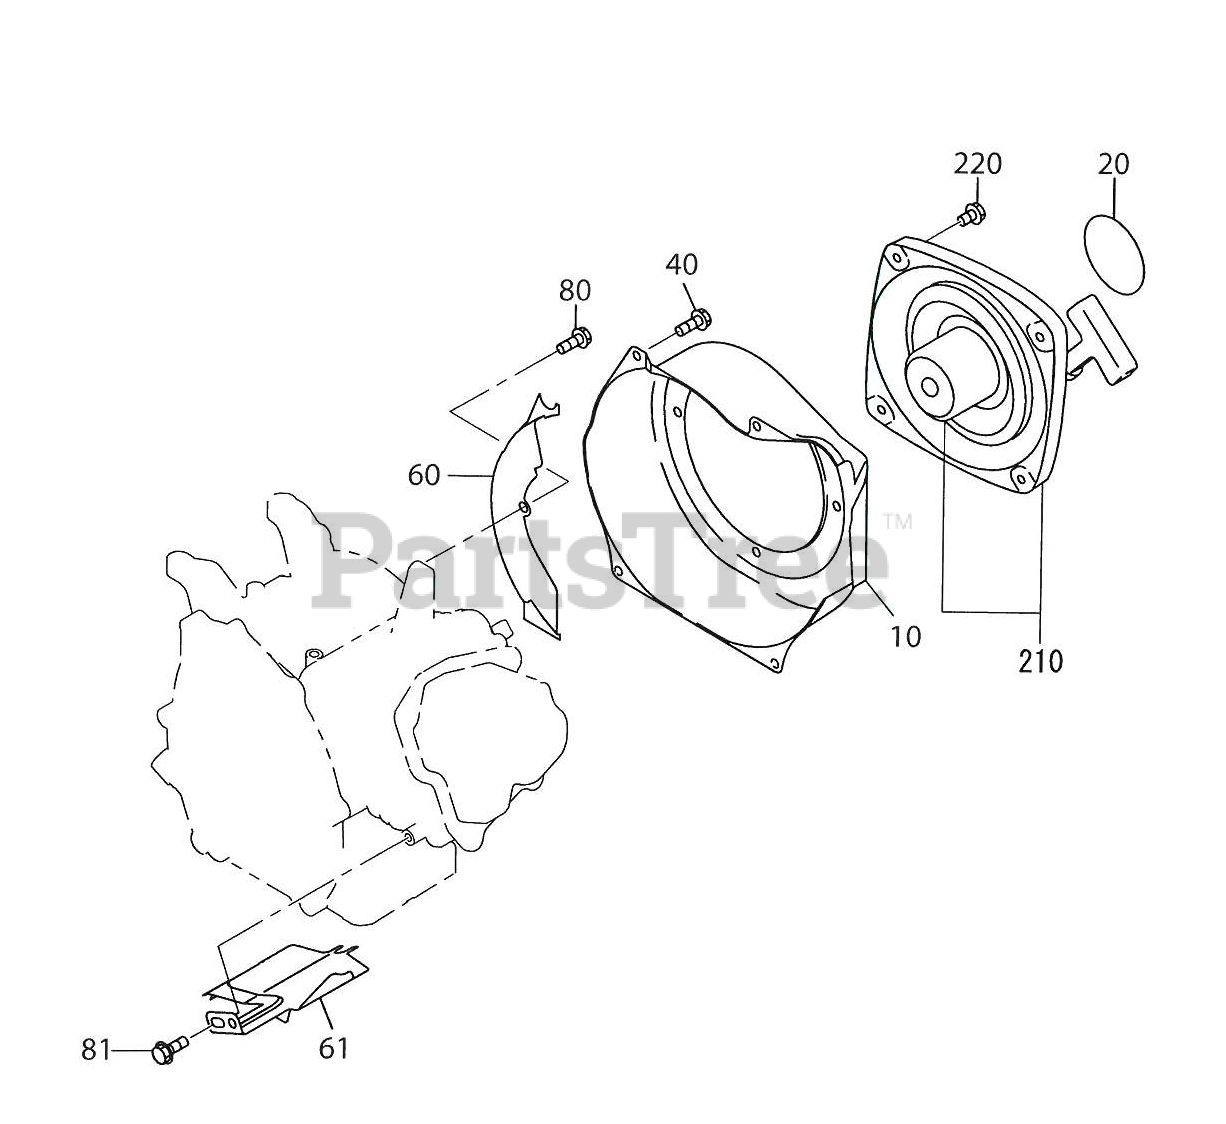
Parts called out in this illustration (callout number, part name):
10	BLOWER HOUSING CP
20	LABEL,TRADEMARK
60	BAFFLE 1 CP, CASE
61	BAFFLE 2, HEAD
210	RECOIL STARTER AY
220	BOLT AND WASHER
